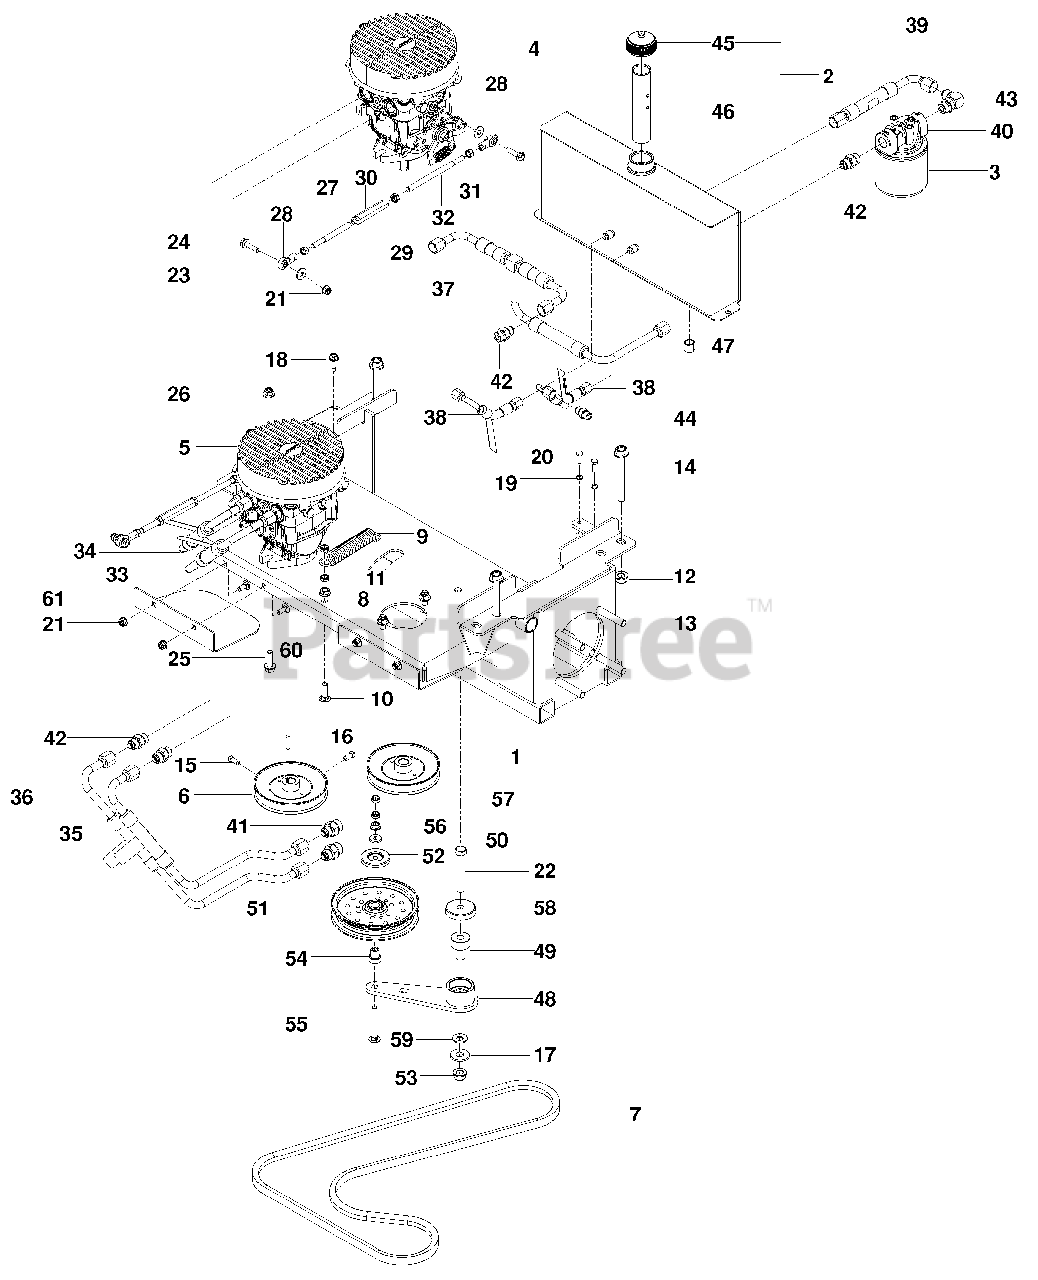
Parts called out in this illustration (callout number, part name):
1	Frame, Sub
2	Bolt 7/16-20 X 1 1/2 Hex Nyl
3	Filter, 25 Micron
4	Pump, 16Cc Rt
5	Pump, 16Cc Lt
6	Pulley, Pump, 17Mm
8	Nut 3/8-16 Hex Whizlk
9	Spring, Pump
10	Bolt 3/8-16 X 1 1/4 Rd Hd
11	Nut 3/8-16 Hex Jam Nyloc
12	Nut 1/2-13 Hex Flg Nyloc
13	Bolt 1/2-13 X 2 3/4 Hex Nyloc
14	Bolt 1/2-13 X 4 Hex Flg
15	Screw 5/16-18 X 5/8 Set
16	Key, Metric
17	Washer 1/2 Flat
18	Bolt 5/16-18 X 1 Thd Frm
19	Washer 1/4 Split Lock
20	Bolt 1/4-20 X 5/8 Hex Nyloc
21	Nut 5/16-18 Hex Flg Nyloc
22	Bolt 1/2-13 X 3 1/4 Hex Nyloc
23	Washer 5/16 Std Flt
24	Screw 5/16-18 X 1 1/4 Tpblt
25	Screw 3/8-16 X 1 1/4 Hex Flg
26	Nut 3/8-16 Hex Flg Nyloc
27	Linkage, Control, Ft
28	Ball End, Rt
29	Nut 3/8-24 Hex Jam
30	Turnbuckle 3/8
31	Nut 5/16-24 Hex
32	Linkage, Control, Rr
33	Line, Hydraulic, Rt-A
34	Line, Hydraulic, Rt-B
35	Line, Hydraulic, Lt-A
36	Line, Hydraulic, Lt-B
37	Line, Hydraulic, Charge
38	Line, Hydraulic, Case
39	Line, Hydraulic, Suction
40	Filter Head
41	Straight Connector
42	Straight Connector
43	Elbow 90O Adj
45	Cap, Hydraulic
46	Tube, Anti-Splash
48	Arm, Idler, W/ Bearings
49	Pivot, Bearing
50	Washer 3/8 Thick
51	Idler Pulley
52	Shield, Dust
53	Nut 1/2-13 Hex Flg Nyloc
54	Pivot, Idler
55	Bolt 3/8-16 X 2 3/4 Rd Hd
56	Nut 3/8-16 Hex Whizlk
57	Nut 3/8-16 Hex Jam Nyloc
58	Shield, Dust
59	Washer 1/2" Belleville
60	Bolt 5/16-18 X 3/4 Rd Hd
61	Shield, Pulley
